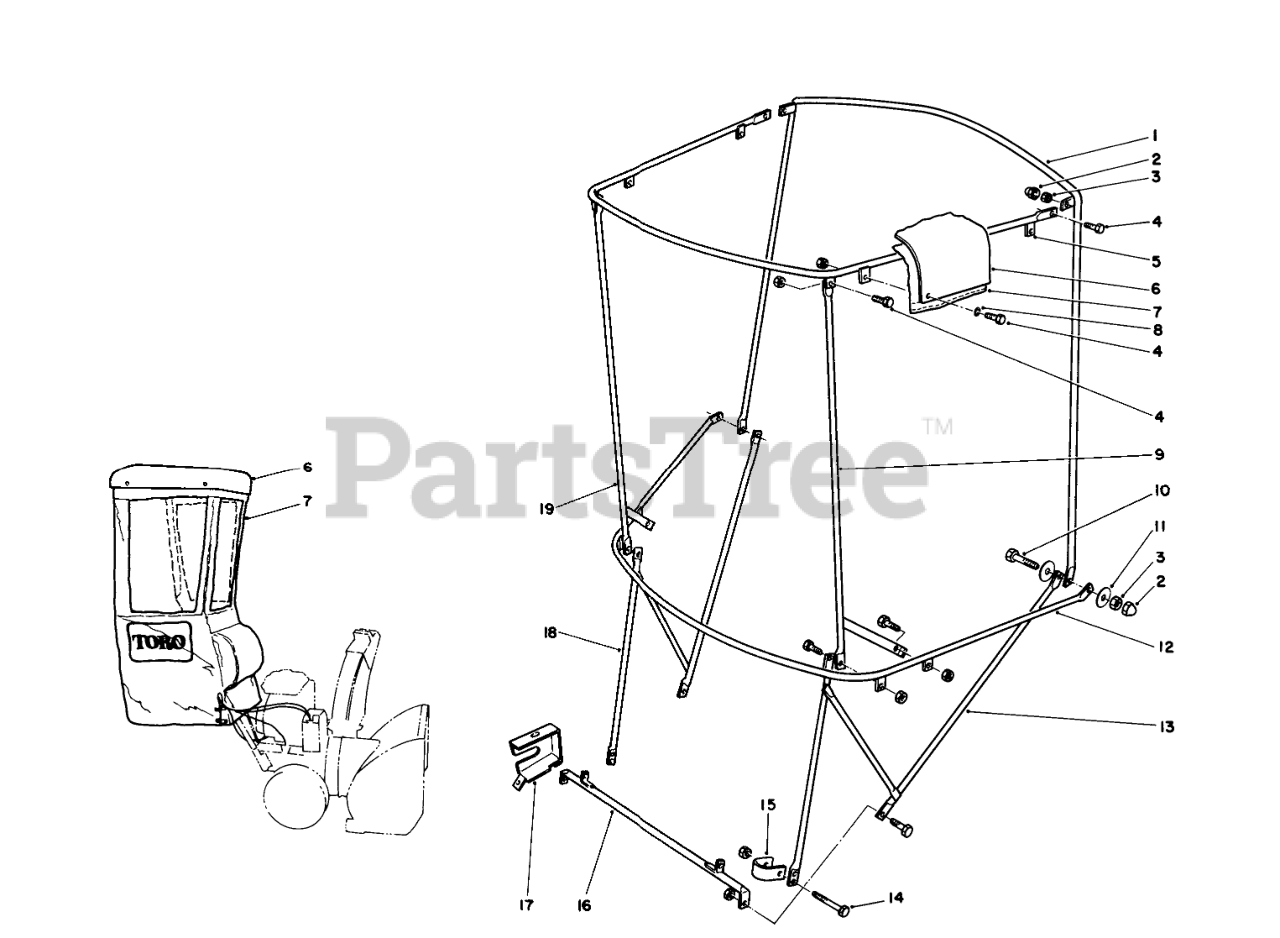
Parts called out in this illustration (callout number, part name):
1	VERTICAL BOW
2	CAPLUG
3	NUT-HEX, SIDE DEFORM
4	SCREW-HH
5	FRAME - TOP
6	Top-Plasitic
7	Cover-Vinyl
8	WASHER-FLAT
9	CORNER POST - LH
10	SCREW-HH
11	WASHER-FLAT
12	HORIZONTAL BOW
13	Bracket-LH
14	SCREW-HH
15	CLAMP
16	Bracket-Base
17	COVER-LOCK, LEVER
18	BRACKET-RH
19	CORNER POST - RH
